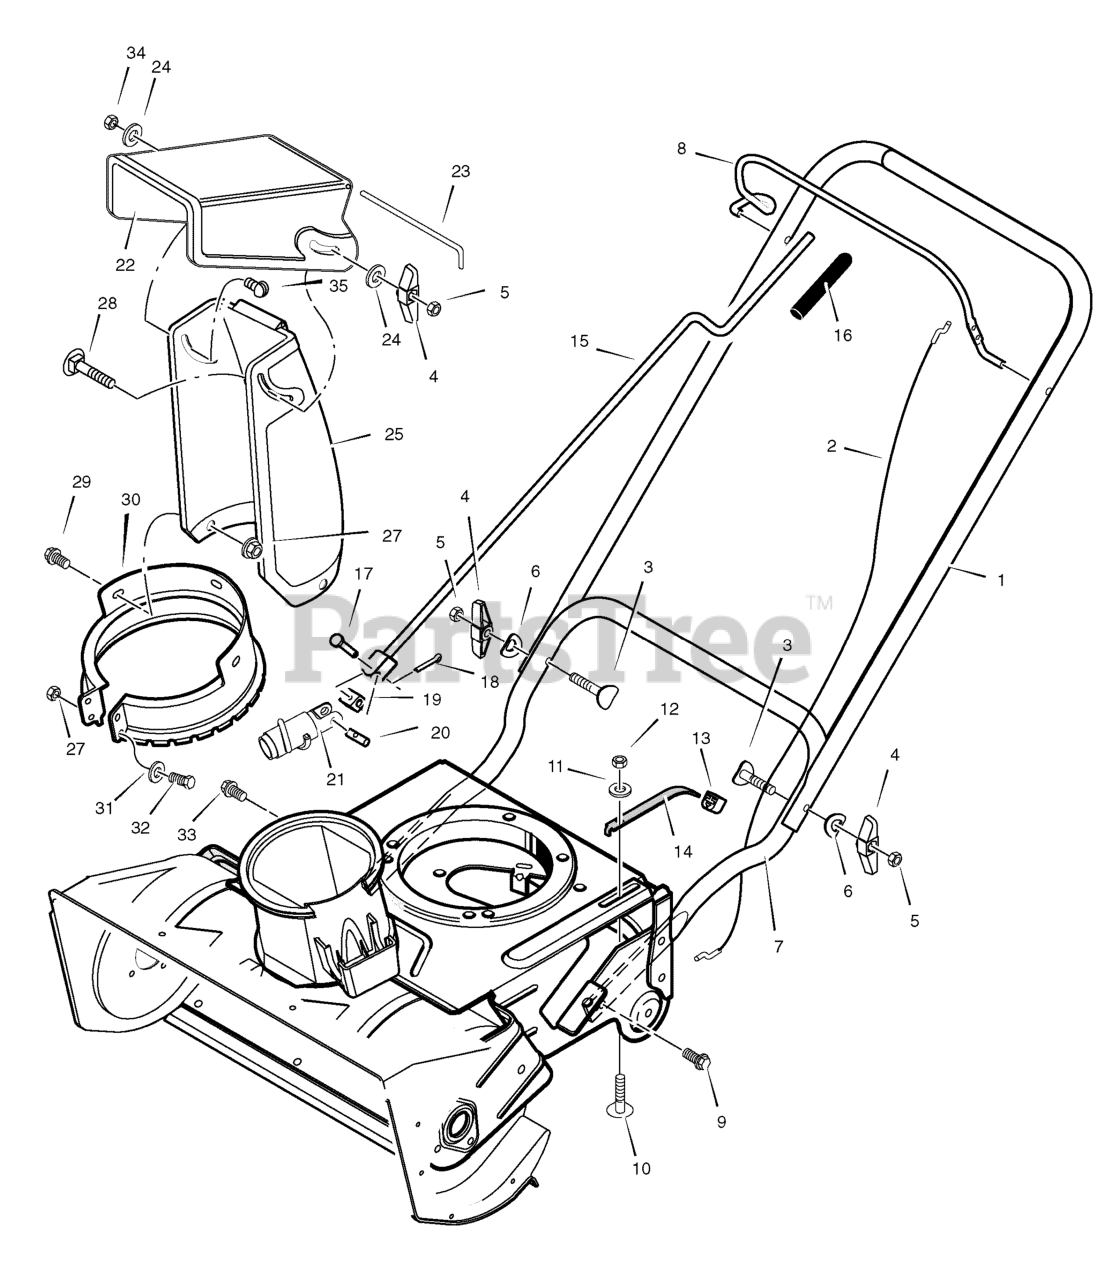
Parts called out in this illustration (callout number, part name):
1	Handle, Upper
2	Cable, Auger Drive
4	Knob
5	Nut
7	Handle, Lower
8	Lever, Auger Drive
9	Screw
13	Bushing, Tensioner
14	Bracket, Cable Tensioner
15	Rod, Crank
16	Grip, Crank Rod
17	Pin, Clevis
18	Pin, Cotter
19	Block, Universal Pivot
21	Gear, Worm
22	Deflector
23	Pin, Pivot
24	Washer
25	Chute, Discharge
30	Ring, Chute
31	Washer
33	Bolt
34	Locknut
